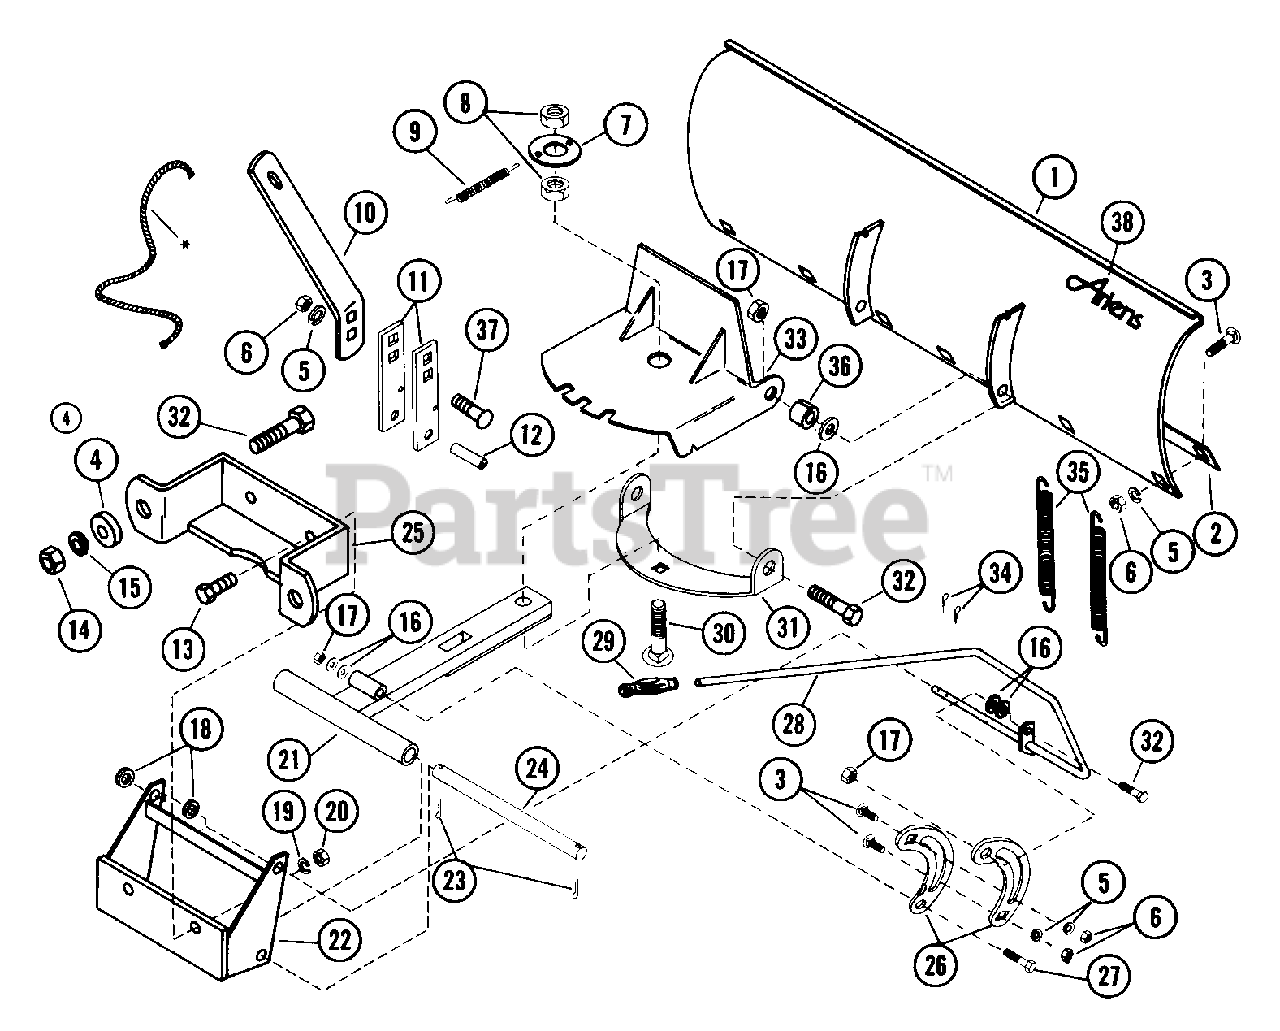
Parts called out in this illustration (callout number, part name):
1	40 INCH SNOW BLADE
2	WEAR BAR
3	BLT-RDHDSQSHNK .38-16X1.00 PL
5	WSHR-LK .375X.115 HVY PL
6	NUT-HEX .375-16
7	LATCH SPRING WASHER
8	BLT-RDHDSQNK .75-10X3.0
9	SG-TENS .106X.56X2.75 WLD 10
10	PIVOT BLOCK EXTENSION
11	BAR PIVOT LOCK
12	PIN-ROLL .250X1.00
13	BLT-HEX .25-20X1.00 PL GR5
14	NUT .50-13 PL
15	WSHR-LK .500X.151 HVY PL
16	WSHR-FL-STL .531X1.062X.095 PL
17	NUT-LK-CTR .50-13
18	WSHR-FL-STL.656X1.312X.095 PL
19	WSHR-LK .250X.077 HVY PL
20	NUT-HEX .250-20 PL
21	PUSH TUBE ASSEMBLY
22	MOUNT BRACKET
23	@PIN-CTR .16X1.25 EXTPRSQCT YZ
24	PIVOT ROD
25	TRACTOR MOUNT
26	LIFT LINK
27	BLT-HEX .50-13X3.00 PL GR2
28	LIFT HANDLE
30	BLT-RDHDSQNK .75-10X3.0
31	LOWER PIVOT PLATE
32	BLT-HEX .50-13X1.50 PL GR2
33	UPPER PIVOT PLATE
34	PIN-HAIR INT .09X.188 PL
35	SG-TENS .125X.81X6.50 WLD 10
36	PIVOT BUSHING
37	BLT-RDHDSQNK .38-16X1.25 PL
38	DECAL - ARIENS
